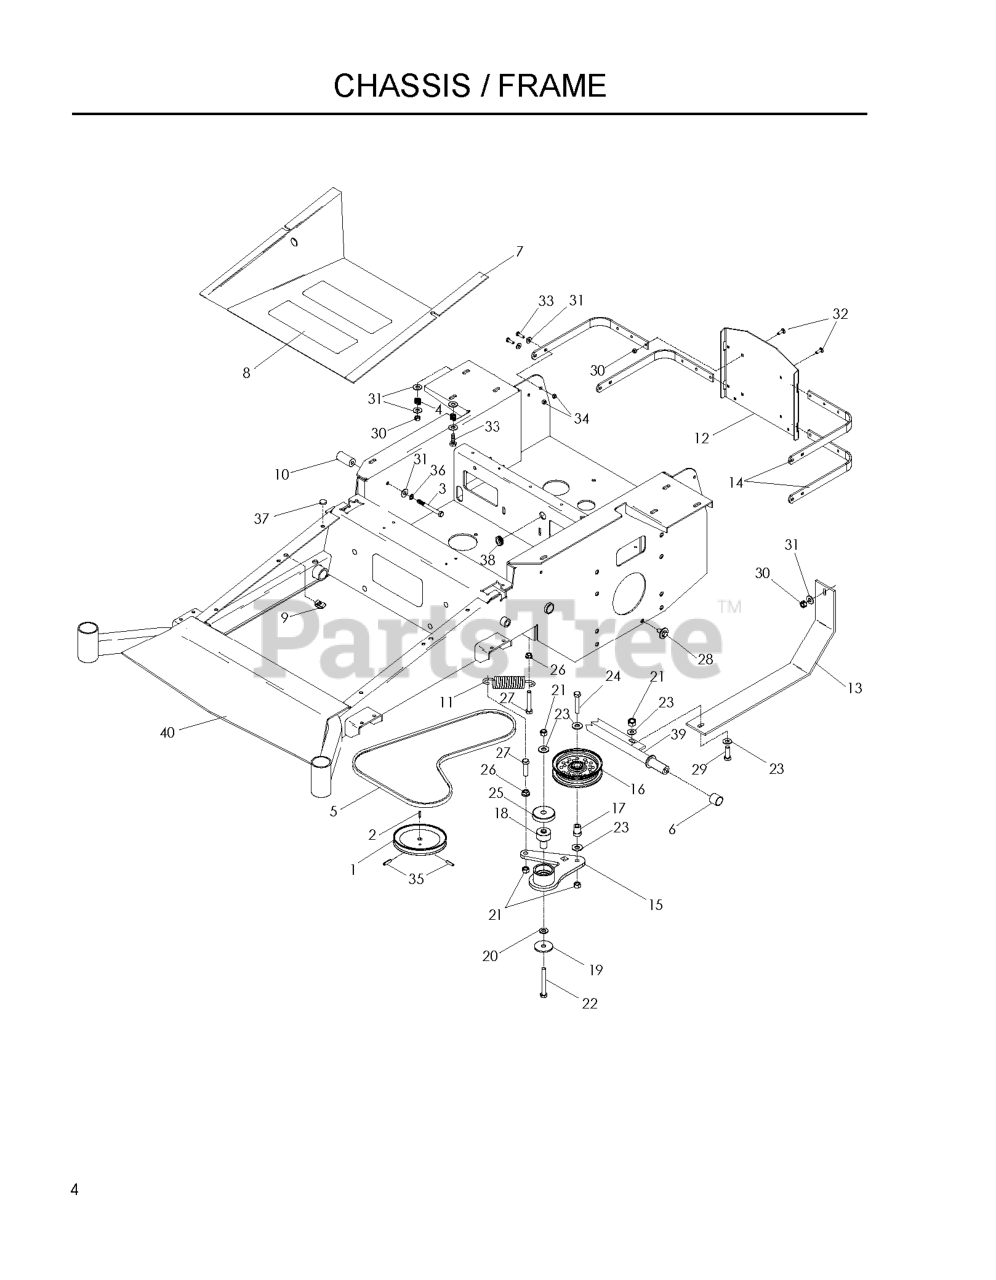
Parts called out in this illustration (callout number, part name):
2	KEY 5 MM SQ X 25 MM
3	HCS 5/16C X 4
5	PUMP BELT
6	SPACER, STRUT
7	FOOT PLATE WIDMT
8	ANTI-SKID PAD
9	U-CLIP 5/16-18 NUT RETAINER
10	TANK SPACER
12	XP GUARD, BLACK
13	SKID PLATE
14	ENGINE SHROUD BRKT
15	ARM, IDLER - W/BEARINGS
16	IDLER PULLEY
17	BUSHING, IDLER FLANGE
18	PIVOT, BEARING
19	WASHER, 3/8 SPEC
20	WASHER 3/8 SAE FLAT
21	NUT 3/8-16 NYLOC
22	HCS 3/8C X 3
23	WASHER 3/8 FLAT
24	HCS 3/8C X 2
25	SHIELD, DUST
26	NUT 3/8C WHIZ
27	HCS 3/8C X 1 1/2
28	BLADE BOLT/WASHER
29	HCS 3/8-16X1.GRD.5.ZD
30	NUT 5/16C CENTERLOCK
31	WASHER 5/16 FLAT
32	BOLT 5/16C X 3/4" CARRIAGE
33	HCS 5/16C X 1
34	NUT 5/16 NYLOC
35	5/16 DIA ROLL PIN
36	WASHER.LOCK.HVY.HLCL.SPR.5/16
37	GROMMET, BUMPER
38	GROMMET, FUEL LINE
39	CROSS SHAFT, STRUT - BLK
40	FRAME W/DECALS 72"
